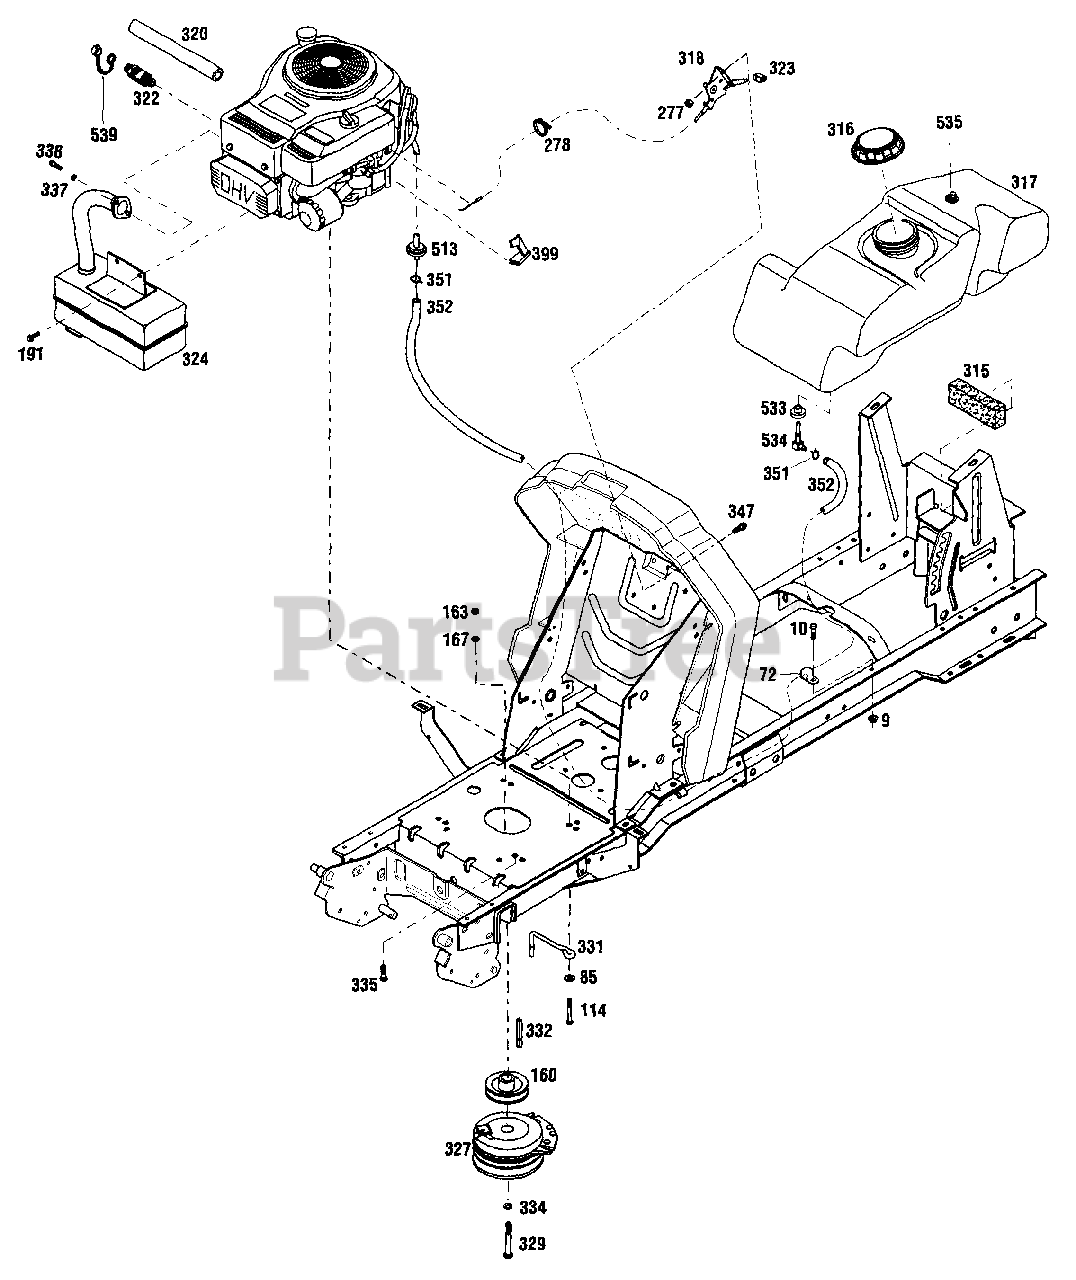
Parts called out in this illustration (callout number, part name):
9	Flange Nut, 5/16-18
10	Hex Head Screw, 5/16-18 x 3/4
85	Flat Washer, 3/8
114	Hex Head Screw, 3/8-16 x 1-1/2
160	Engine Sheave
163	Hex Nut, 3/6-16
167	Lockwasher 3/8
191	Flange Screw, 1/4-20 x 3/4
277	Keps Locknut, 10-24
278	Cable Tie
315	Fuel Tank Pad
317	Fuel Tank
318	Throttle Choke Control
320	Oil Drain Hose
322	Oil Valve Assembly
323	Control Knob
327	Electric Clutch
329	Hex Head Screw, 7/16-20 x 3
331	Clutch Retainer
332	Square Key, 1/4 x 1-1/2
334	Spring Lock Washer, 7/16
335	Hex Head Screw, 3/8-16 x 1
337	Special Lock Washer
338	Screw, 5/16-18 x 3/4
347	Machine Screw, 10-24 x 3/4
351	Hose Clamp
352	Fuel Line
513	Fuel Filter
533	Bushing
534	Fuel Tank Elbow
535	Fuel Tank Vent
539	Oil Drain Cap
